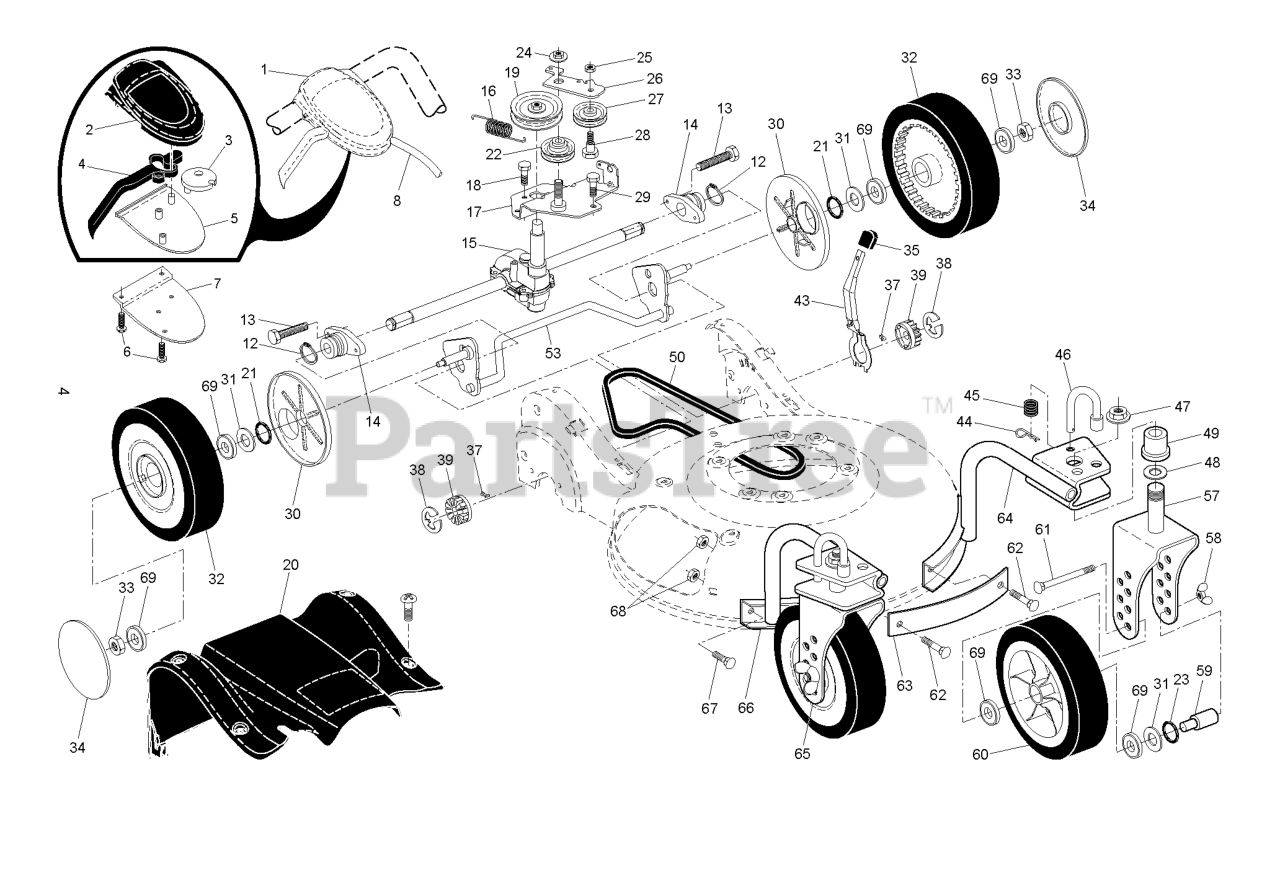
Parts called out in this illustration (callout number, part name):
1	Drive Control Assembly, Complete
2	COVER TOP AUTO WALK CONTROL
3	PULLEY.CAM.DRIVE.CONTROL.HV
4	LEVER.BLACK
5	COVER BOTTOM AUTO WLK CONTROL
6	SCREW, PHILLIPS HEAD 10 X 5/8
7	BRACKET.DRIVE.CONTROL.MOUNT.BL
8	ASM.CABLE.
12	RETAINING RING (2 2)(3 2)
13	HINGE SCREW
14	BEARING / AXLE SUPPORT
15	TRANSMISSION.21.HV.RWGD.AW/EZ
17	BRACKET, GEAR CASE / DRIVE
19	RP PULLEY.DRIVE.EZ
20	COVER.DR.ASM.408006X418.CE
21	O-RING..070X.487.NEOPRENE
22	PULLEY.IDLER.V-BELT
23	O-RING
24	NUT.HEX.FLANGE.3/8-16.LOCKNUT
25	NUT.CENTERLOCK.5/16-
26	ARM.IDLER.BZP
27	IDLER PULLEY
28	SHOULDER BOLT
29	SCREW 14-20 X 5/8
30	DUST COVER, WHEEL
31	WASHER.FLAT.1/2
32	WHEEL.9X2.25.LP.TIGER.BLACK
33	NUT.HEX.FLANGE.3/8-16.LO(3 2)
34	HUBCAP.WHEEL.5.SPOKE.SILVER
35	KNOB.SELECTOR.SPRING.BLACK(3 2
37	PAWL, DRIVE
38	E-RING 7/16 RE
39	PINION.14.TEETH.FGD
43	LEVER, SELECTOR, HEIGHT, REAR
44	SPRING RETAINER
47	NUT.HEX.FLANGE.3/8-16.LOCKNUT
48	WASHER.FLAT.1/2
50	BELT, DRIVE
53	SHAFT.ASM.REAR.TORQUE.HV.BZP
57	BRACKET.WHEEL.ASM.LT.CASTER.OR
58	NUT.WING.5/16-18.YELLOW
60	WHEEL.9X2.25.LP.TIGER.SILVER
61	CARRIAGE BOLT
63	STRAP.FRONT.CASTER.ORANGE
64	SUPPORT.TUBE.ASM.LT
65	BRACKET.WHEEL.ASM.RIGHT.ORANGE
66	SUPPORT.TUBE.ASM.RT
68	NUT
69	BEARING.8".WHEEL
